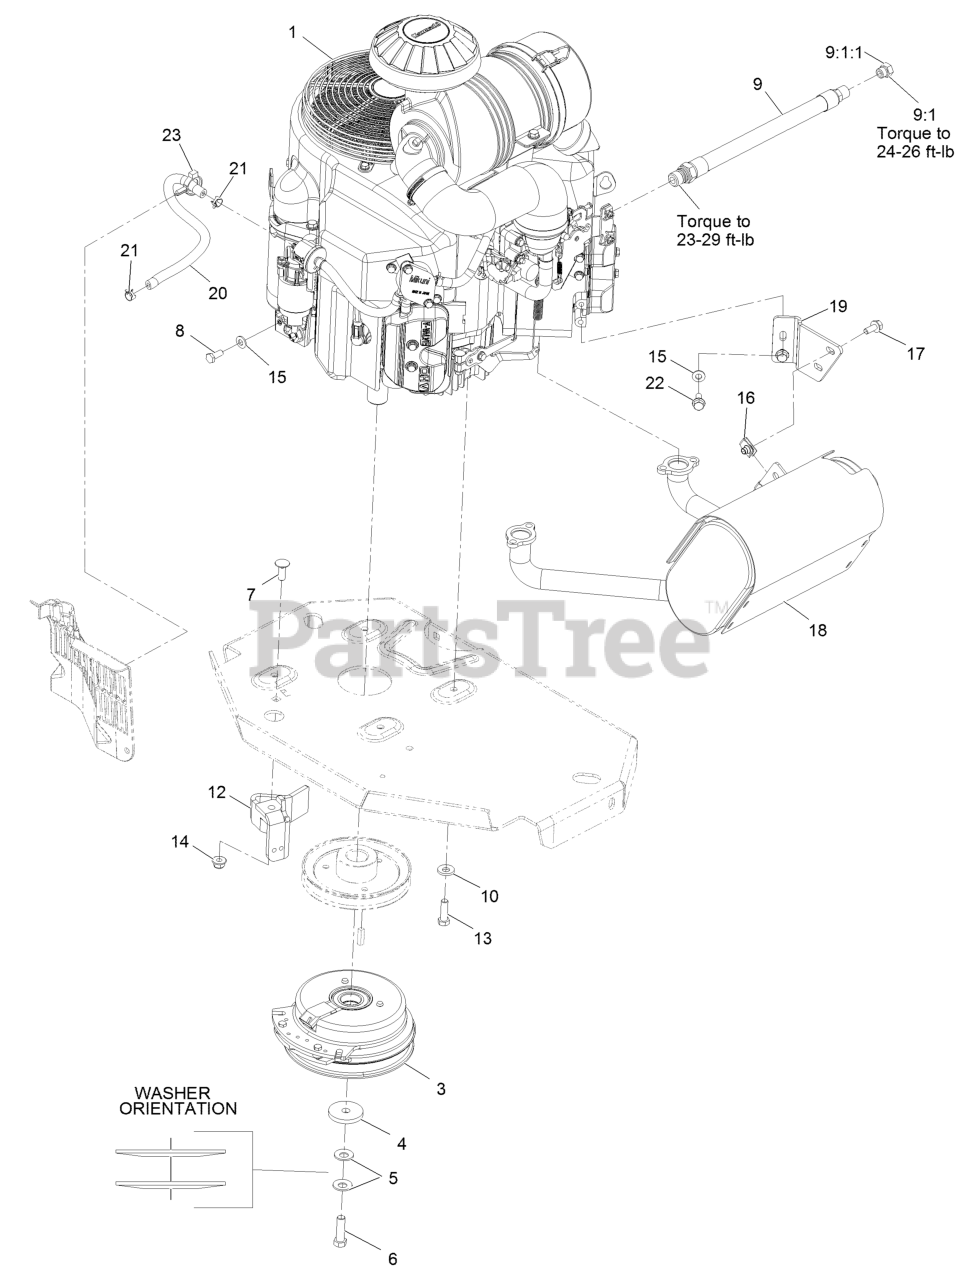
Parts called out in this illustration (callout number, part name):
3	CLUTCH KIT
4	WASHER-CLUTCH
5	WASHER-SPRING
6	SCREW-HH 7/16-20 X 1 1/2 W/LOCTITE
7	SCREW-CARR
8	SCREW-HH
9	ENGINE OIL DRAIN HOSE ASM
9:1	PLUG-HH
9:1:1	O-RING
10	WASHER-BELLEVILLE
12	CLUTCH-ANCHOR
13	SCREW-HH
14	NUT-HF, NI
15	WASHER-SPRING
17	SCREW-HHF
18	MUFFLER
19	BRACKET-MUFFLER
20	HOSE-FUEL
21	CLAMP-HOSE
22	SCREW-HHF
23	CLAMP-HOSE
